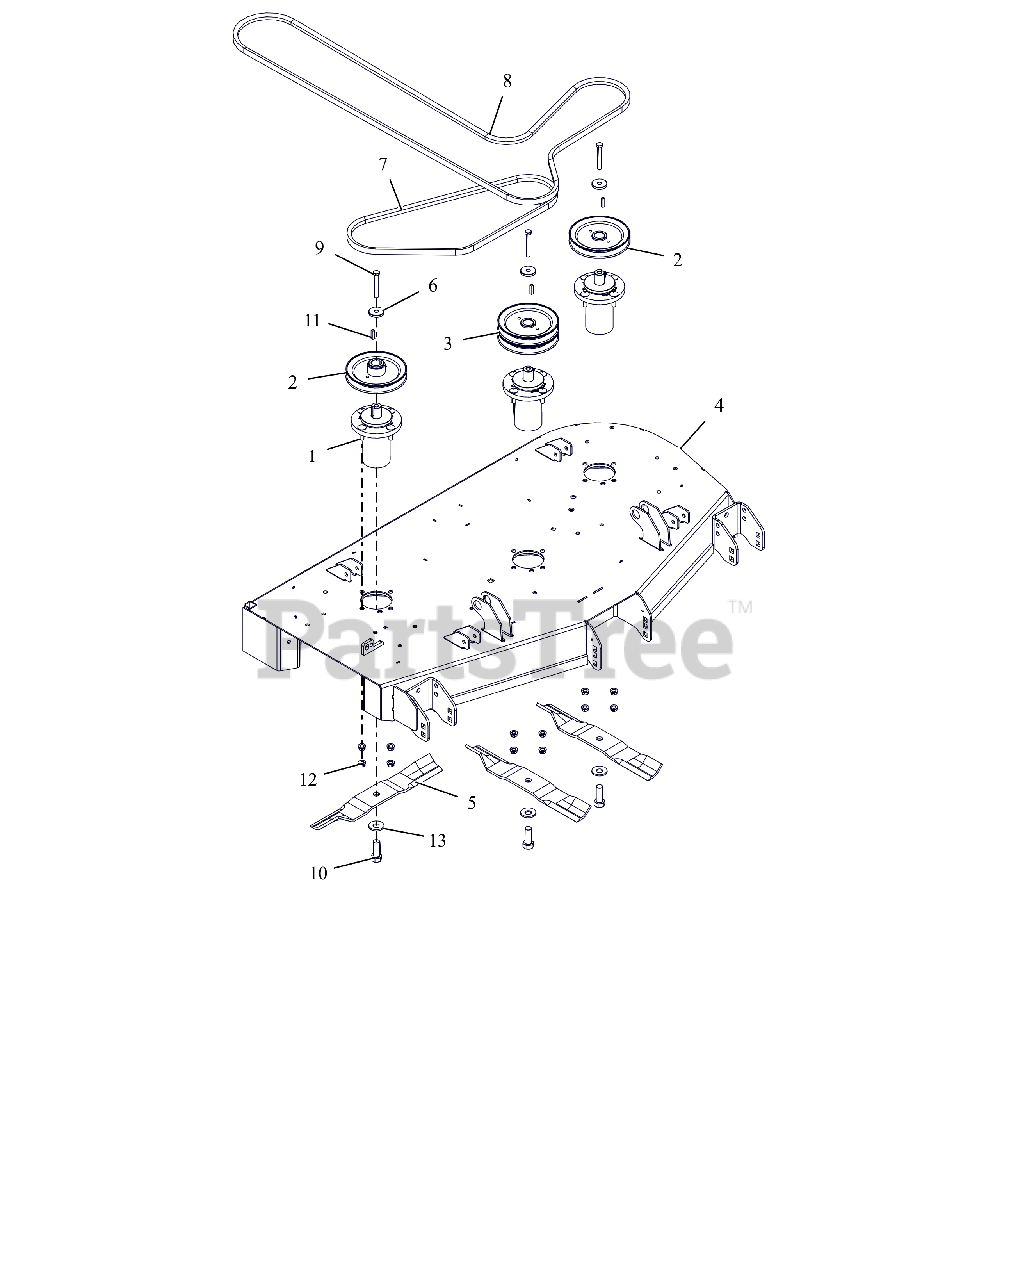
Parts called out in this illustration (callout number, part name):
1	ASM, MAINT FREE ALUM SPINDLE
2	PULLEY, SINGLE-1"ID X 6" OD
3	PULLEY, DOUBLE
4	KIT,DECK-48" W/DECALS - ARIENS
5	BLADE, 16.19" MOWER (HI-LIFT)
6	RETAINER, SHEAVE
7	V-BELT, B-COGGED
8	V-BELT, HB SECTION
9	BLT-HEX .38-16X2.75 GR8 YWZC
10	BLT-HEX .62-18X1.75 GR8 YWZC
11	KEY, SQ .25X.25X1.00 RC 40-50
12	NUT-LK-CTR-FLG .38-16 YWZC
13	WSHR-BLVL .669X1.535X.138
